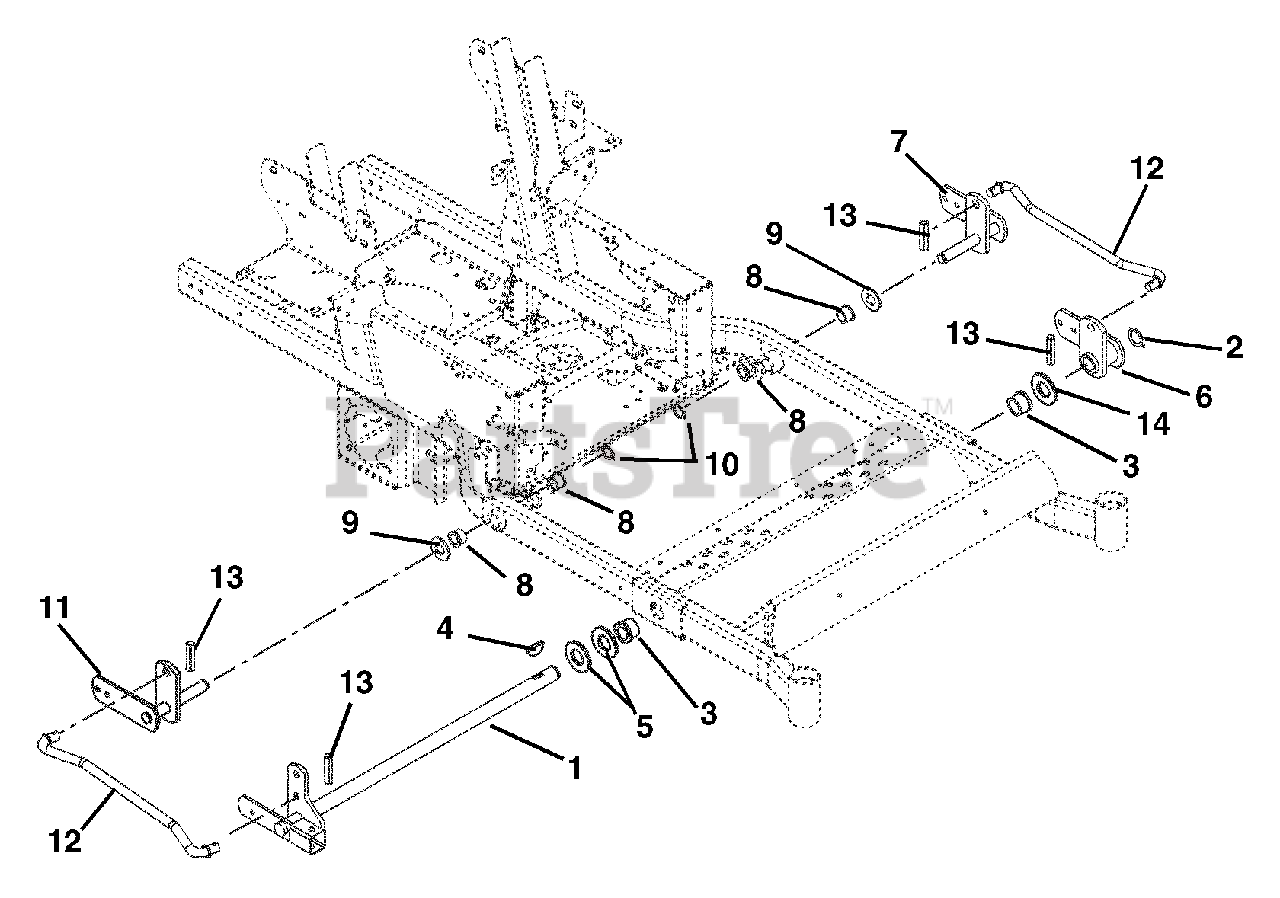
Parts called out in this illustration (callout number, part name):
1	MOWER LIFT
2	RG-RTNG-EXT 1.00X.078
3	BSHG-FLG1.020X1.385X.75X1.75NY
4	KEY-WDRF .25X1.00 HRD #15
5	WSHR-FL-STL- 1.062X2.0X.134 YZ
6	WMT, FRONT MOWER LIFT-LH
7	WMT, REAR LIFT ARM -LH
8	BSHG-FLG .762X1.0X.580X1.48 NY
9	WSHR-HDND-THRST .758X1.23X.031
10	RG-RTNG-EXT .689X.078
11	WMT, REAR LIFT ARM - RH
12	ROD, LIFT ASSIST 16.35"
13	PIN-ROLL .250X1.25
14	WSHR-HDND-THRUST 1.00X1.55X.03
